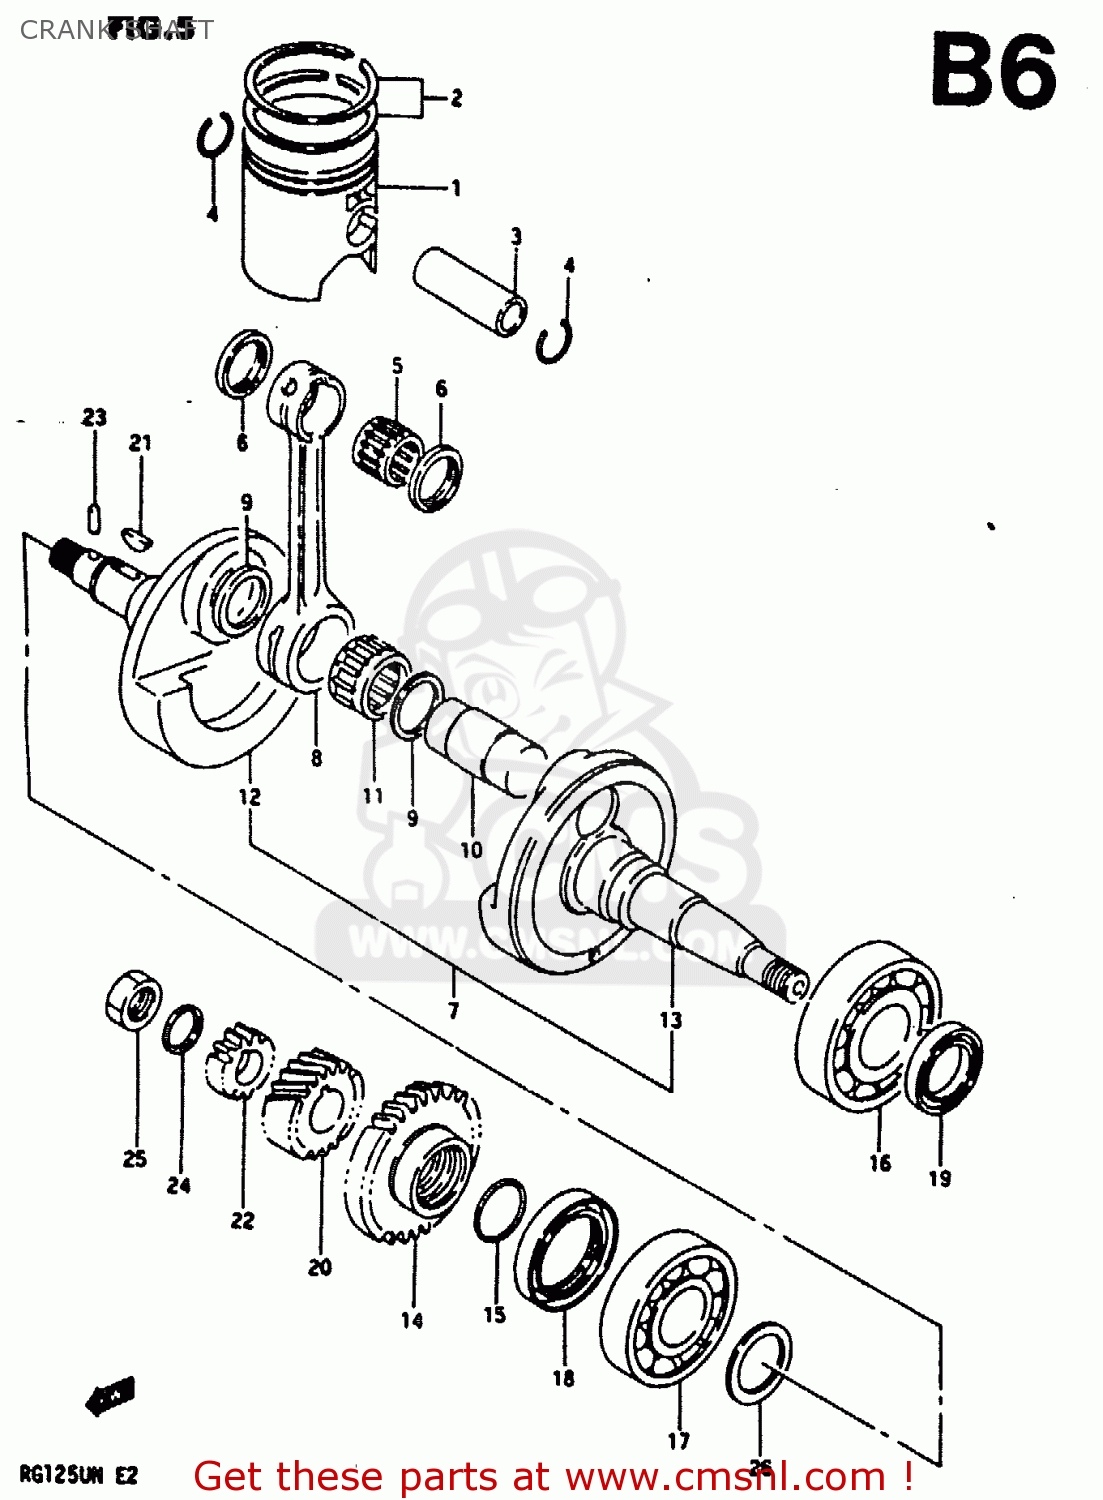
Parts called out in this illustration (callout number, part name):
1	PISTON
2	RING SET,PISTON
3	PIN,PISTON
4	RING,SNAP 16MM
5	BEARING(16X20X17.8)
6	WASHER
7	CRANKSHAFT ASSY
8	ROD,CONNECTING
9	WASHER(22X27.5X1.5)
10	PIN,CRANK
11	ROLLER BEARING (22X28X1
12	CRANKSHAFT, RH
13	CRANKSHAFT, LH
14	GEAR, CRANK BALANCER DRIVE
15	O RING(D:2.3,ID:24.4)
16	BEARING 28X68X18
17	BEARING, RH (25*62*17)
18	OIL SEAL, RH (36*52*8)
19	SEAL,OIL(25X36X6)
20	GEAR,PRIMARY DRIVE
21	KEY
22	GEAR,WATER PUMP DRIVE
23	PIN
24	WASHER
25	NUT
26	PASTILHA
